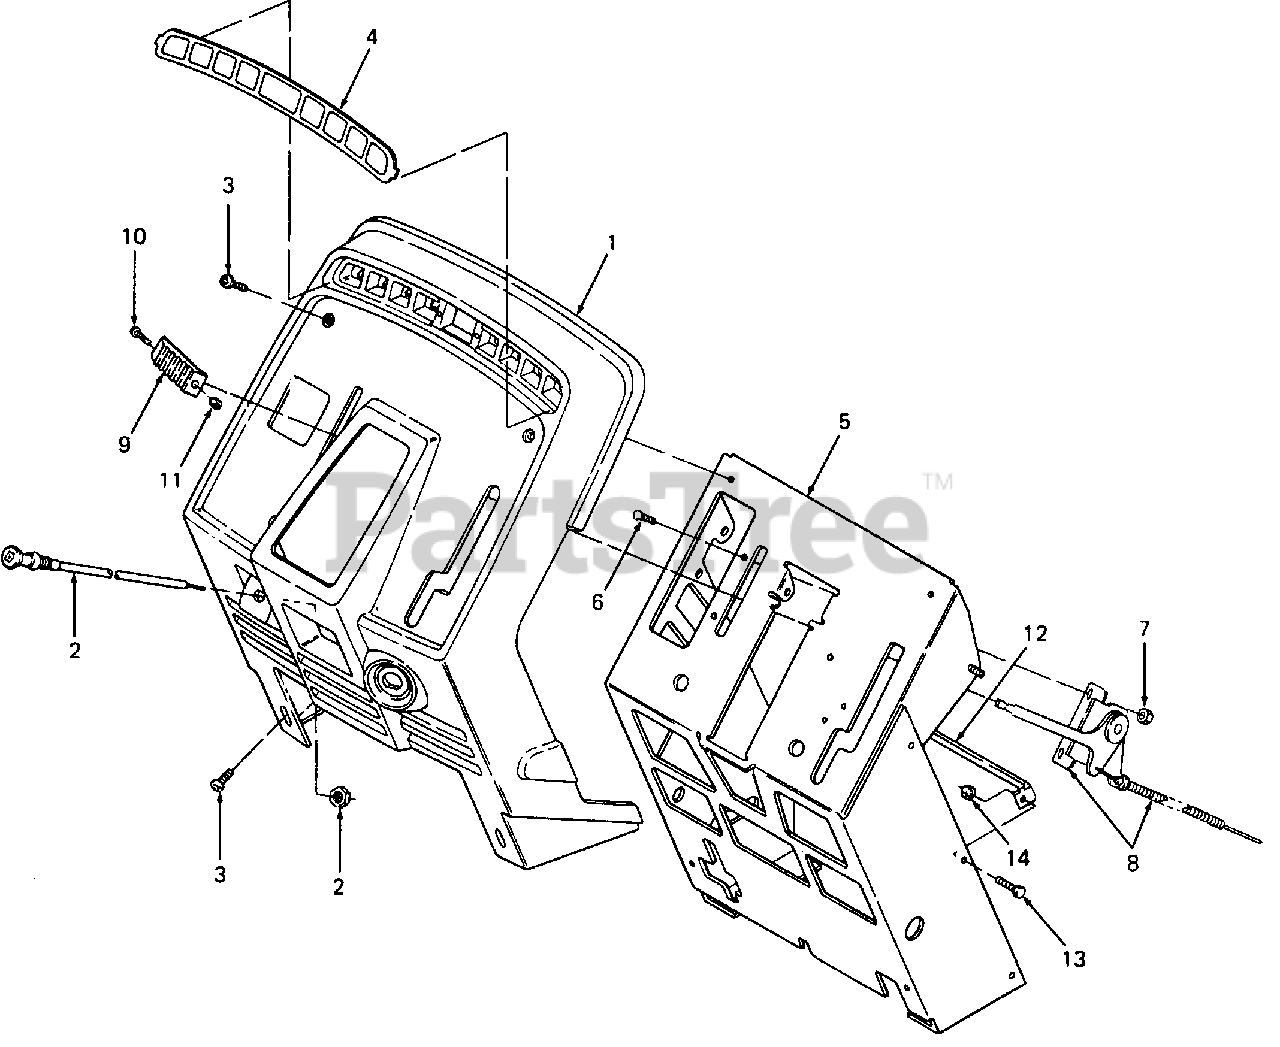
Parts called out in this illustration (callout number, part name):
1	Panel, Instrument
2	Choke Cable w/Nut
3	Screw, Pan Hd Cutting, #10-24 x .75 Lg
4	Label, Dash
7	Nut, Hex Keps, #10-32
8	Control, Throttle
9	Knob, Throttle
10	Screw, Cross Rec Truss Hd, #8-32 x .38 Lg
11	Nut, 8-32
12	Bracket, Harness
13	Screw, Hex Cap, 1/4-20 x .50 Lg GR5
14	Nut, Hex Patch Lock, 1/4-20
